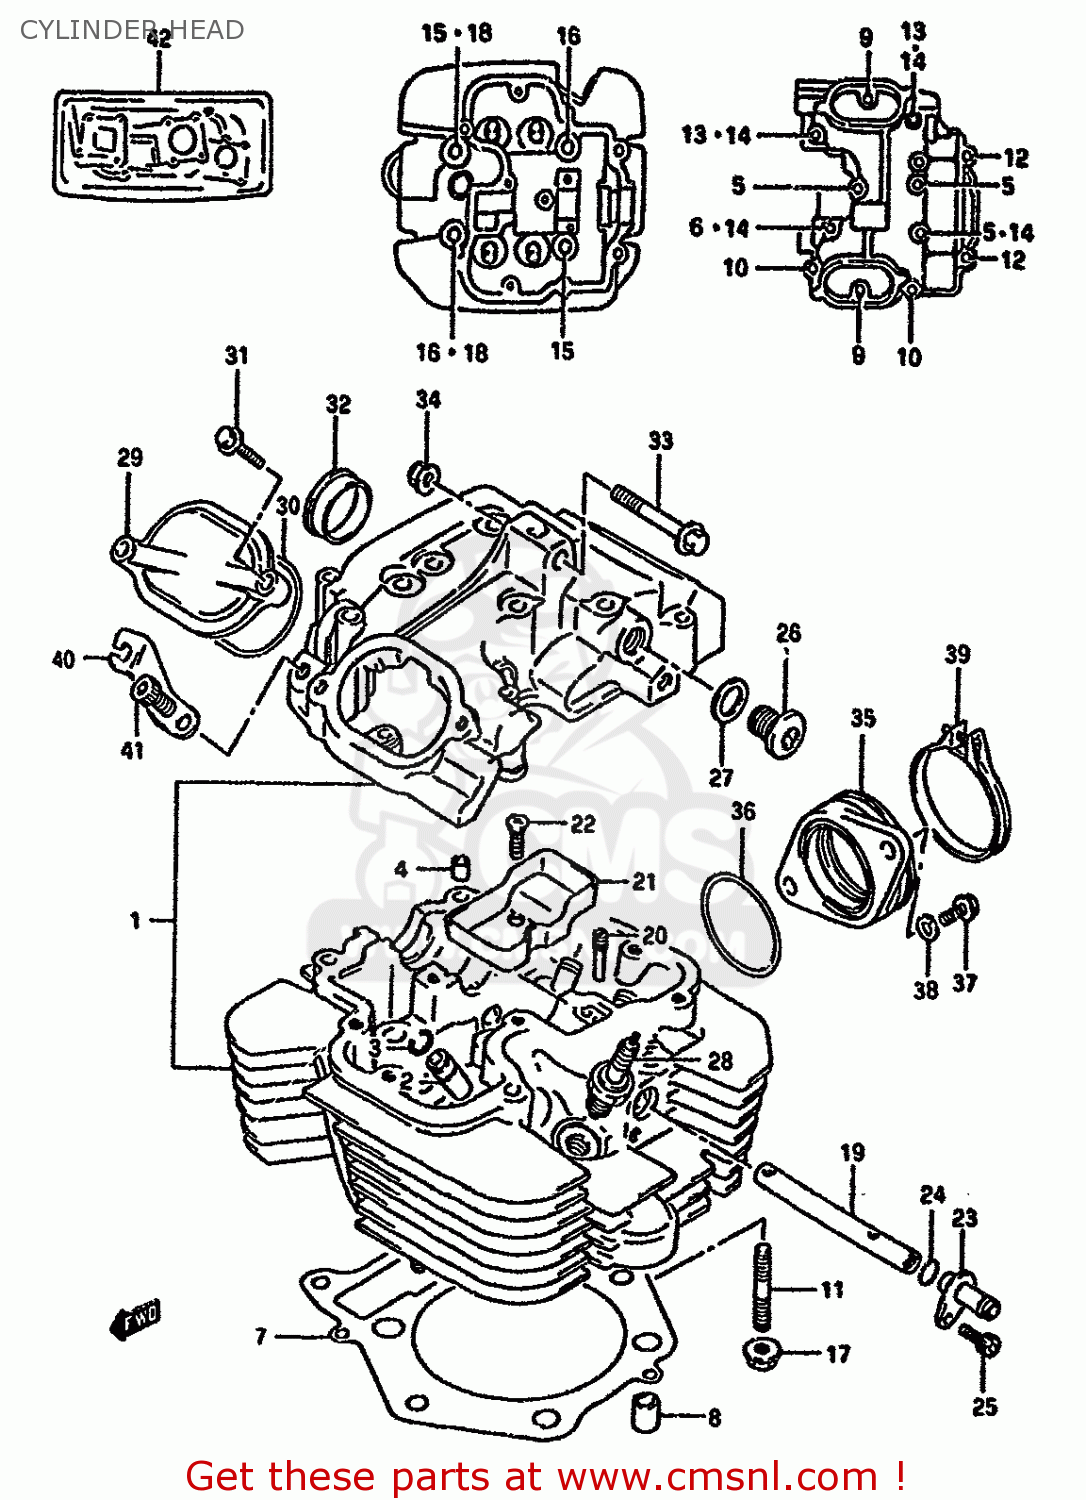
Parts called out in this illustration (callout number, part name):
1	HEAD ASSY,CYLINDER
2	GUIDE,VALVE
3	RING,SNAP
4	PIN(6.2X8X11)
5	BOLT (6X60)
6	BOLT 6X55
7	GASKET,CYLINDER HEAD (NAS)
8	PIN
9	BOLT
10	BOLT
11	STUD
12	BOLT
13	BOLT (6X60)
14	GASKET (NAS)
15	BOLT(10X190)
16	BOLT(10X215)
17	NUT
18	GASKET(10.5X22X2) (NAS)
19	PIPE,CYLINDER HEAD OIL
20	SCREW (L:19.5)
21	PLATE,CYLINDER HEAD CHAMBER
22	SCREW
23	UNION,CYLINDER HEAD OIL
24	O RING,HEAD GASKET
25	BOLT
26	PLUG
27	GASKET(13.8X18.8X4.8) (NAS)
28	SPARK PLUG DP9EA-9
29	CAP,INSPECTION
30	O RING(D:2.4,ID:23)
31	BOLT
32	PLUG(OD:30)
33	BOLT 8X53
34	NUT
35	PIPE,INTAKE
36	O RING(D:2.4,ID:45.7)
37	BOLT
38	WASHER
39	CLAMP
40	LEVER,DECOMP SHAFT RH
41	BOLT
42	GASKET SET (NAS)
